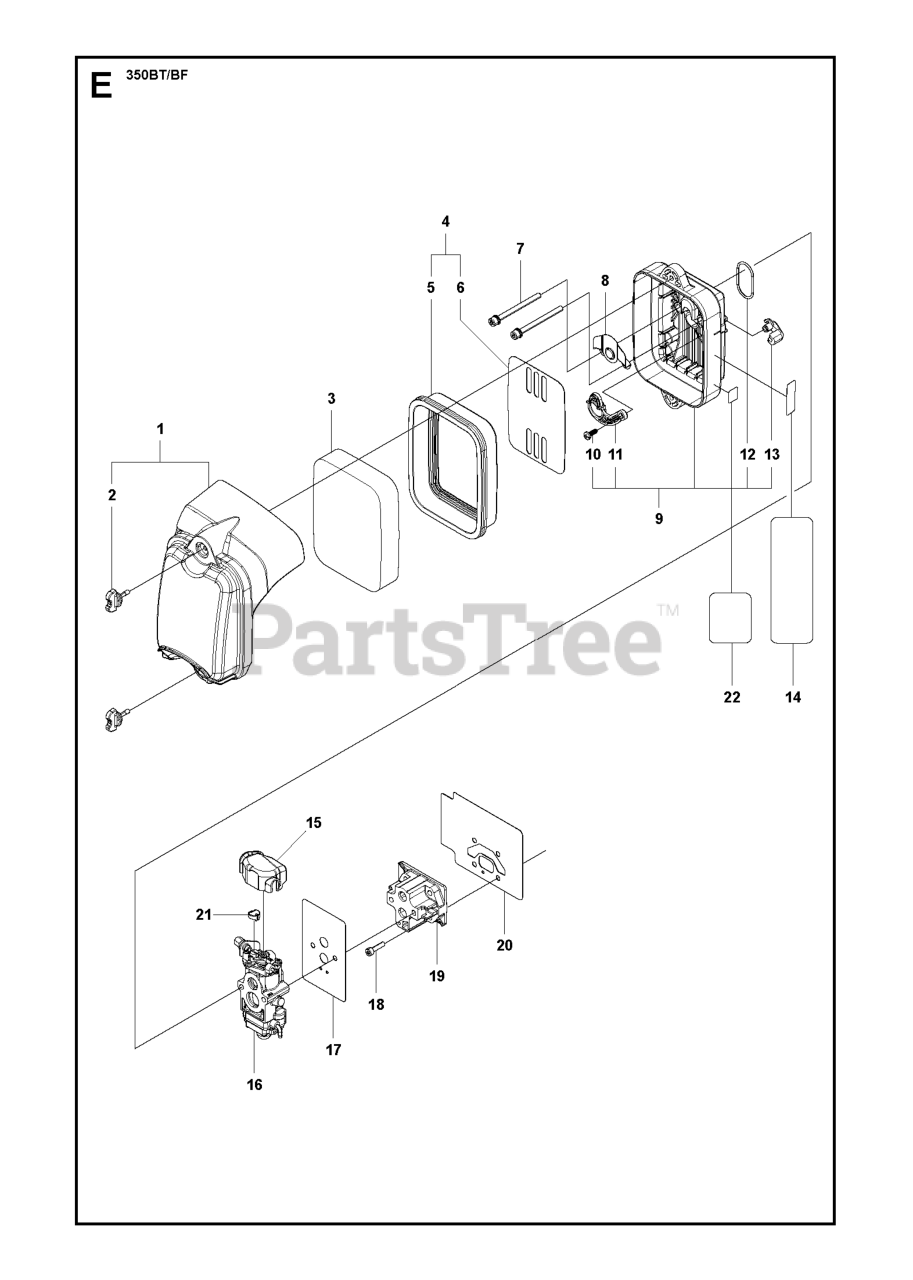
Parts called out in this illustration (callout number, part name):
3	AIR FILTER
6	SCREEN
9	AIR FILTER HOLDER ASSY
14	LABEL,CHOKE
16	CARBURETTOR
19	INSULATION
20	GASKET,INSULATOR
